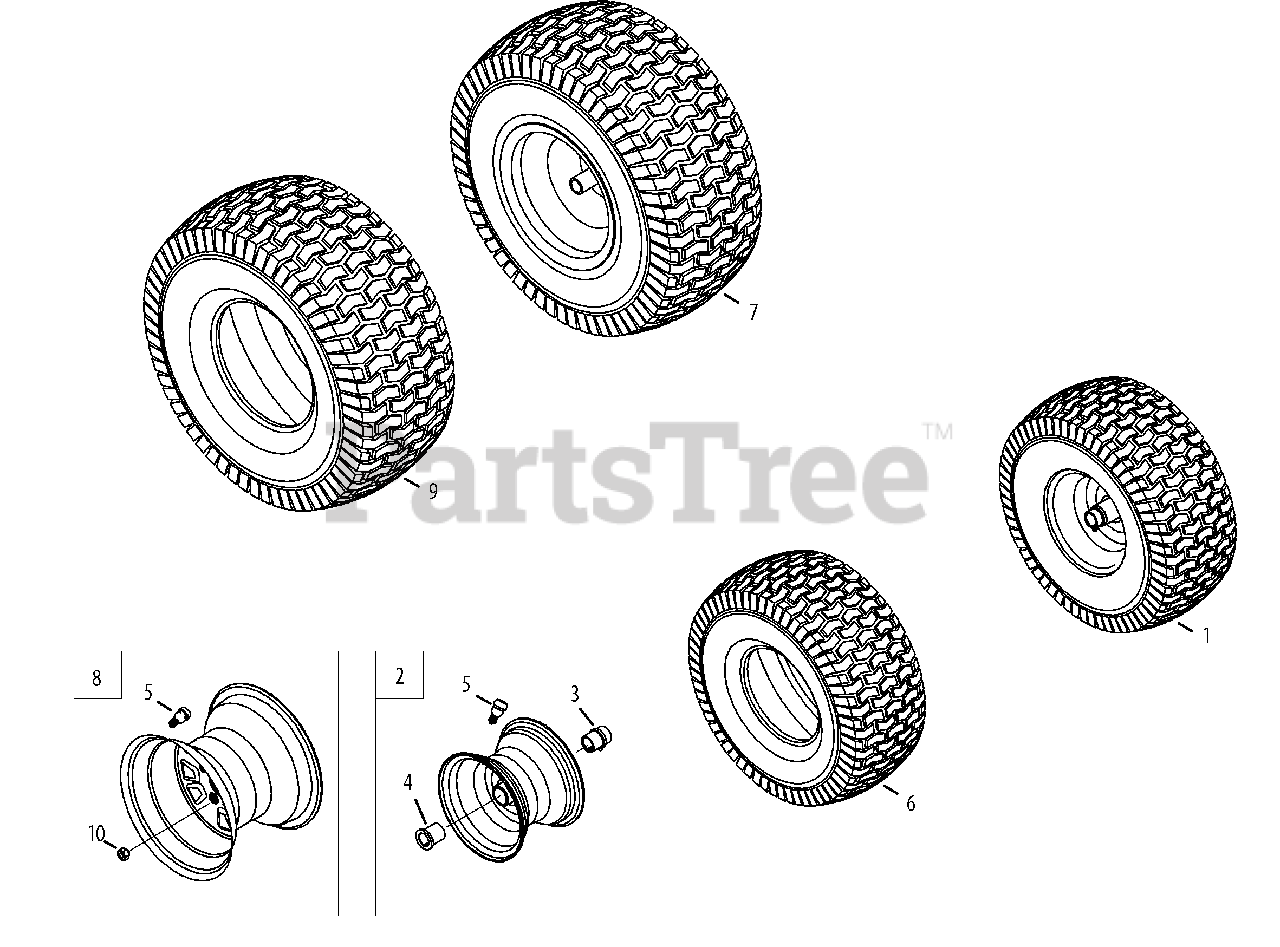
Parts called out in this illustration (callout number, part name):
1	Wheel Ass’y, Complete, 16 x 6 x 5.8
2	Rim Ass’y, 8.0 x 5.3, Flange Bearings
3	Bearing, Flange, .760 ID w/ Fitting
4	Bearing, Flange, .760 x 1.00 x 1.20
5	Valve, Tubeless Air
6	Tire, 16 x 6.5 x 8 Sq Shoulder
7	Wheel, Complete, 23 x 10.5 x 12
8	Rim Ass’y, 12.0 x 7.0
9	Tire, 23 x 10.5 x 12 Sq Shoulder
10	Nut, Lug, 7/16-14
